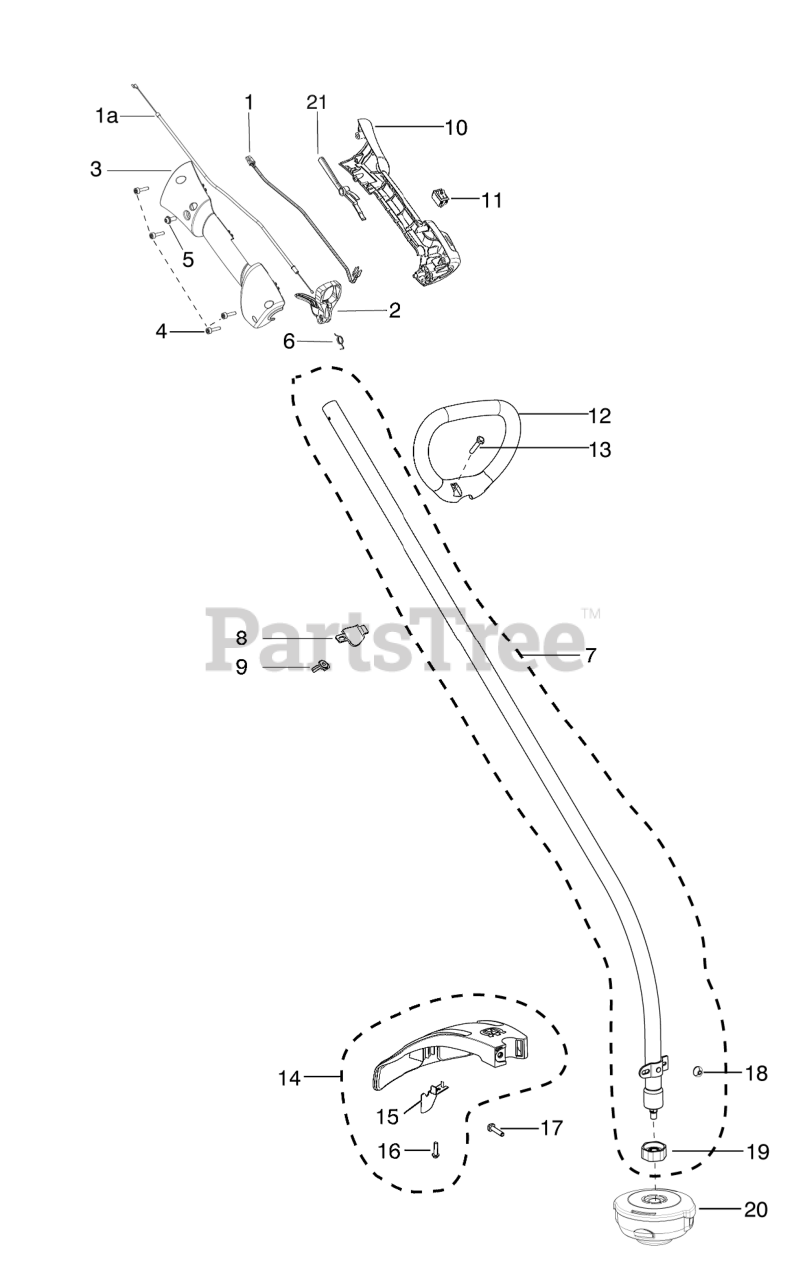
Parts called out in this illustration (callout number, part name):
1	CABLE SHORT CIRCUIT HND
2	TRIGGER THROTTLE HVA ORANGE
3	HSG THROTTLE RIGHT HVA
6	SPRING TRIGGER
7	KIT DRIVE SHAFT
8	CLAMP ASSIST HANDLE
9	WINGNUT, TYPE 2
10	HSG THROTTLE LEFT HVA
11	SWITCH
12	HANDLE ASSIST SOFT
13	BOLT, TYPE 2
14	KIT SHIELD
16	SCREW 10-14X3/4 PLASTITE
17	BOLT, TYPE 2
20	T25 3/8" RH TRIMMER HEAD
21	THROTTLE LOCKOUT HVA ORANGE
